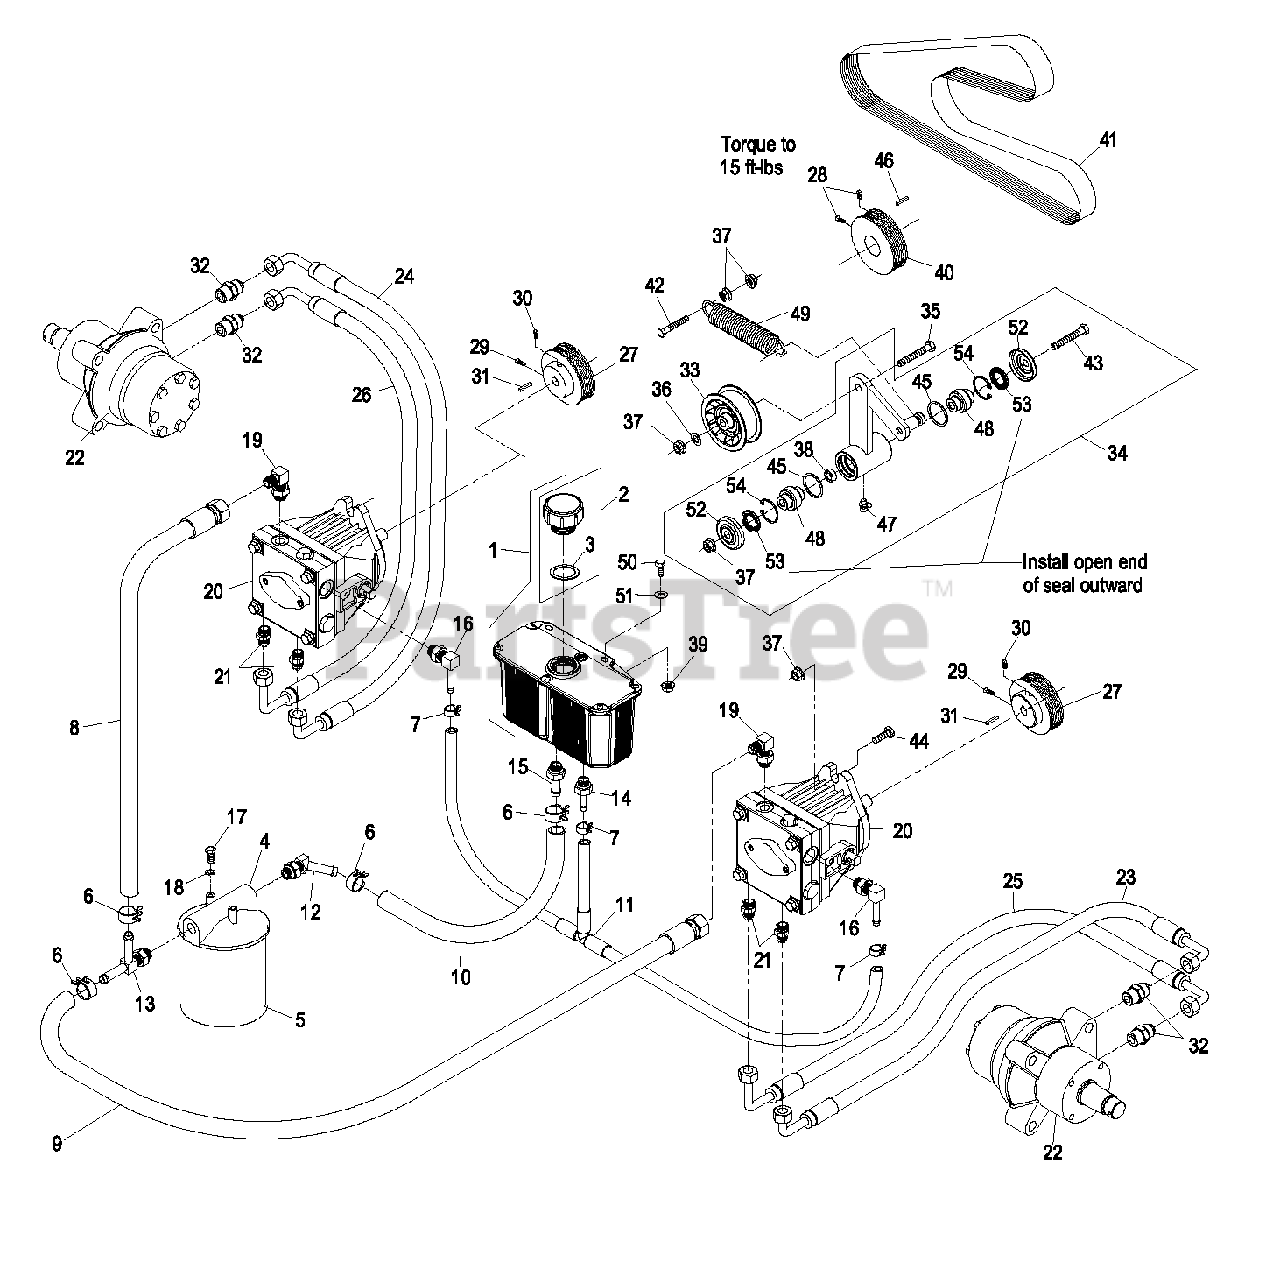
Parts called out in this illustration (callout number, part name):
1	HYD RESERVOIR ASM
2	KIT,HYD RES CAP W/GASKET
3	GASKET-CAP
4	HEAD-FILTER
5	FILTER-25 MICRON, BI-DIRE
5	ELEMENT-FILTER, WINTER
6	CLAMP-HOSE
7	CLAMP-HOSE
8	HYD HOSE ASM
9	HYD HOSE ASM
10	HOSE-HYD
11	HYD HOSE ASM
12	FITTING-BARBED, 45 DEG
13	ADAPTER-RUN, TEE
14	ADAPTER-STRAIGHT
15	ADAPTER-STRAIGHT
16	ELBOW-90 DEG
17	SCREW-HH
18	WASHER-LOCK
19	FITTING-ELBOW, 90 DEG
20	BEARING-THRUST
20	CYLINDER BLOCK KIT
20	SEAL OVERHAUL KIT
20	SHOCK VALVE KIT
21	FITTING-STRAIGHT
22	MOTOR-WHEEL
23	HYD HOSE ASM
23	Hose, Upper Lh (72")
24	HYD HOSE ASM
24	HOSE-RH, UPPER
25	HYD HOSE ASM
25	HOSE-LH, LOWER
26	HYD HOSE ASM
26	HOSE-RH, LOWER
28	SCREW-SET
29	SCREW-SET
30	SCREW-SET
31	KEY-SQUARE
32	FITTING-STRAIGHT
33	PULLEY-FLAT IDLER
34	KIT,PUMP IDLER LZ
35	SCREW-HH
36	WASHER-FLAT
37	NUT-HHF, WHIZ
41	BELT, POLY-V K
42	SCREW-HH
43	SCREW-HH
44	SCREW-HH
46	KEY-SQUARE
47	FITTING-GREASE, 90 DEG
48	BEARING-SPHERICAL
50	SCREW-HH
51	WASHER-FLAT
52	GUARD-TOP
53	SEAL-LIP, SINGLE
54	RING-SNAP
